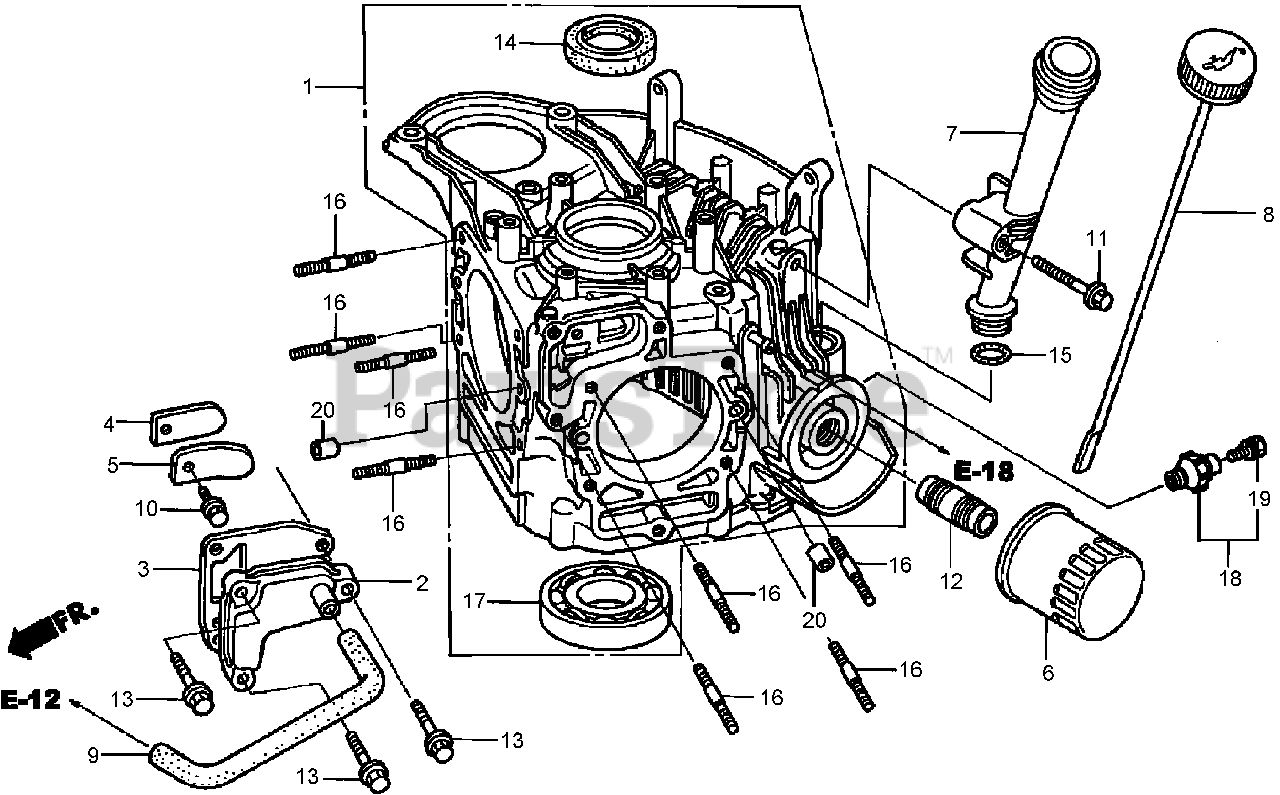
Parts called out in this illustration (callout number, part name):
1	CRANKCASE ASM (840)
2	COVER-BREATHER
3	GASKET-COVER, BREATHER
4	PLATE-VALVE
5	STOPPER-VALVE
6	FILTER-OIL (TOYO ROKI)
7	EXTENSION-FILLER, OIL
8	DIPSTICK-OIL
9	TUBE-BREATHER
10	BOLT-FLANGE (5X10)
11	BOLT-FLANGE (6X45) (C T200)
12	HOLDER-FILTER, OIL
13	BOLT-FLANGE (6X25) (C T 200)
14	SEAL-OIL (35X5X8)
15	O-Ring (22.5X2.2)
16	BOLT-STUD (8X28)
17	BEARING-BALL, RADIAL
18	OIL PRESSURE SWITCH ASM
19	BOLT-WASHER (4X8) (DENSO)
20	Pin-Dowel (8X14)
